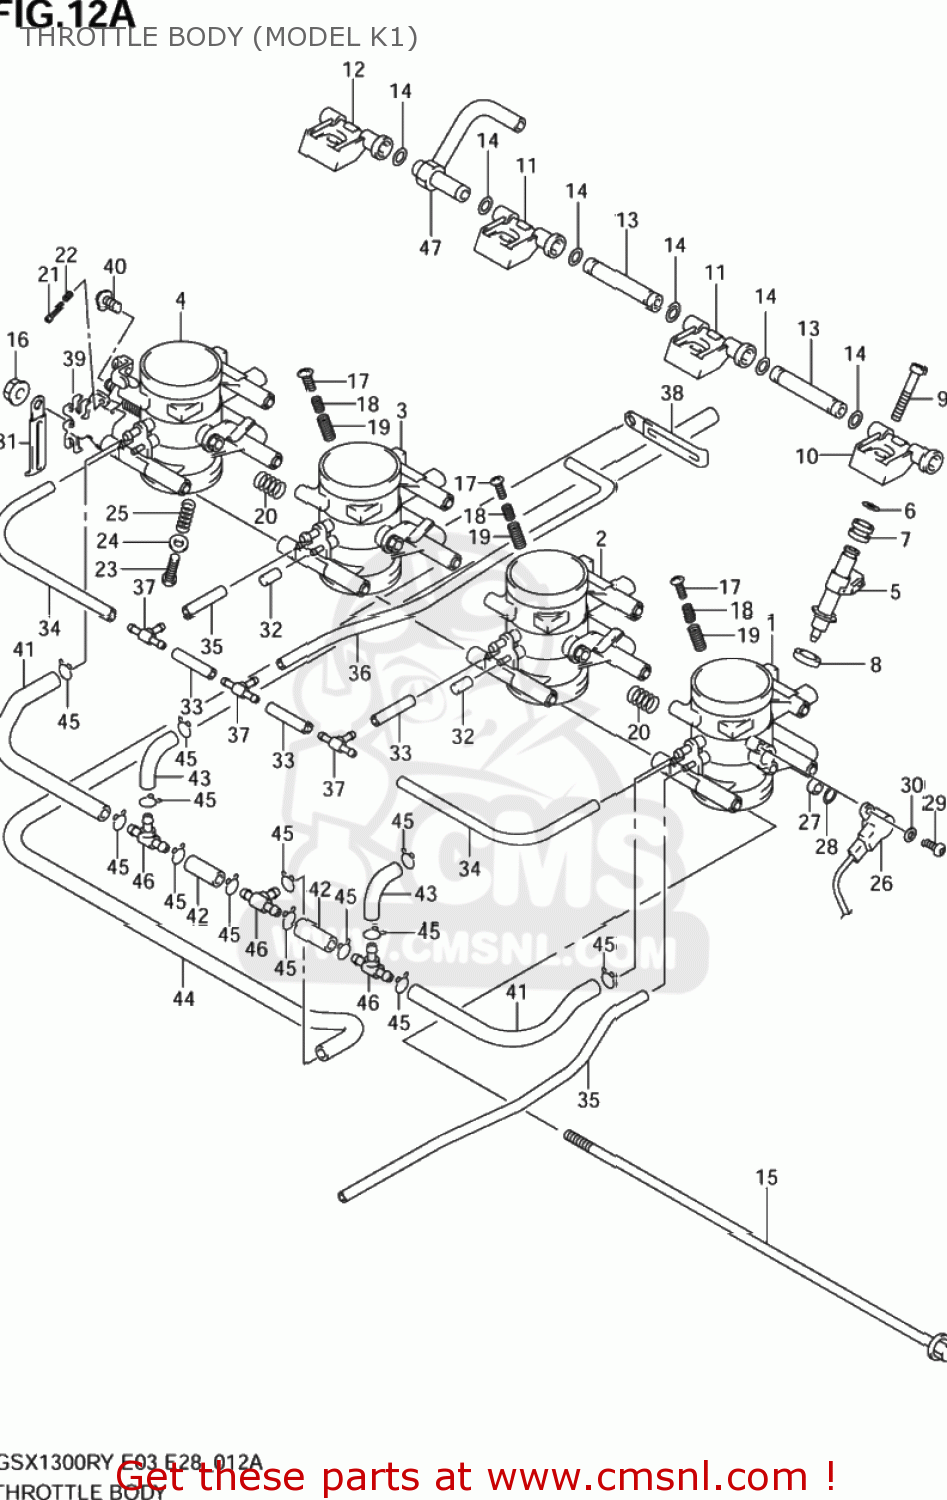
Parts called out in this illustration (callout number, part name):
1	THROTTLE BODY ASSY,L
2	THROTTLE BODY ASSY ML
3	THROTTLE BODY ASSY MR
4	THROTTLE BODY ASSY,R
5	INJECTOR ASSY
6	O RING
7	RING,CUSHION
8	RING,SEAL
9	SCREW
10	JOINT,NO.1
11	JOINT,NO.2,3
12	JOINT,NO.4
13	JOINT
14	O RING
15	BOLT
16	NUT
17	SCREW,STOP
18	SPRING
19	SPRING
20	SPRING
21	SCREW
22	SPRING
23	SCREW,STOP
24	WASHER
25	SPRING
26	SENSOR ASSY,THROTTLE
27	COLLAR
28	O RING
29	SCREW
30	WASHER
31	CLAMP
32	CAP,RUBBER
33	HOSE,RUBBER(L:35)
34	HOSE,RUBBER(L:100)
35	HOSE,RUBBER(L:200)
36	HOSE,RUBBER(L:230+20)
37	JOINT
38	BAND
39	PLATE,STAY
40	SCREW
41	HOSE,RUBBER(L:80+25)
42	HOSE,RUBBER(L:35)
43	HOSE,RUBBER(L:30+30)
44	HOSE,RUBBER(L:440+30)
45	CLIP
46	JOINT
47	JOINT
